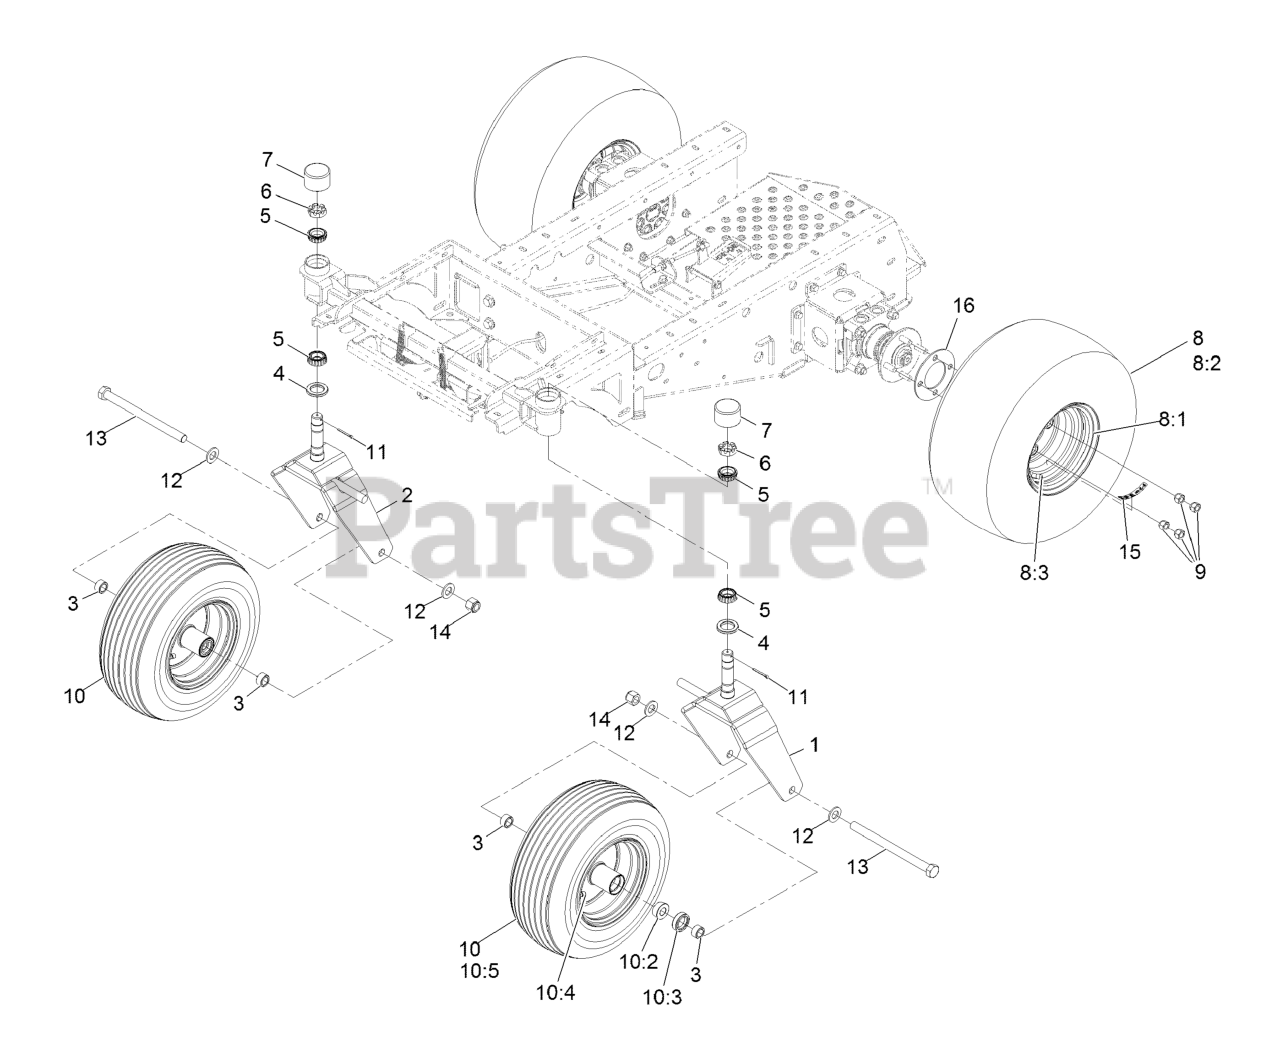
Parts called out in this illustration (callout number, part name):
1	X-REF TO 135-5441-03
2	X-REF TO 135-5446-03
3	SPACER-AXLE
4	SEAL-GREASE
5	CONE-BEARING, OUTER
6	NUT-SHH
7	CAP-DUST, RUBBER
8	WHEEL AND TIRE ASM
8:1	Rim-8 X 7, Black
8:3	Stem-Valve
9	NUT-LUG
10	WHEEL AND TIRE
10:2	BEARING-CONE, TAPERED ROLLER
10:3	SEAL-CASTER
10:4	VALVE
10:5	Tire-Rib
11	Pin-Cotter
12	WASHER-FLAT
13	SCREW-HH
14	NUT-LOCK, NI
15	DECAL-TORQUE, WHEEL HUB LUG
16	SPACER-WHEEL
